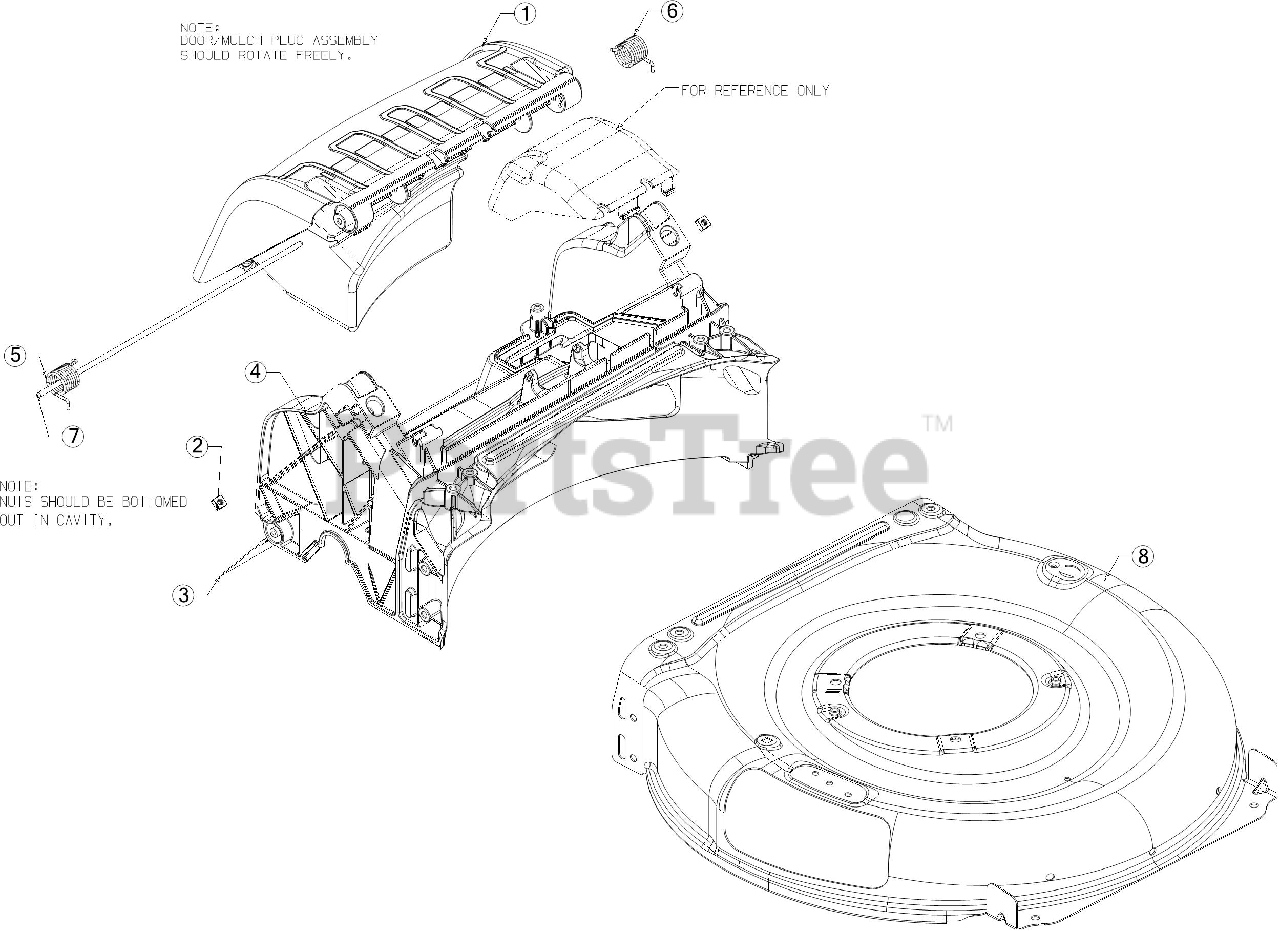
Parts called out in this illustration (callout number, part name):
2	SQUARE NUT 1/4-20
3	TRAILSHIELD
5	TORSION SPRING (RH)
6	TORSION SPRING (LH)
7	REAR DOOR PIVOT ROD
8	21" DECK (3N1)
